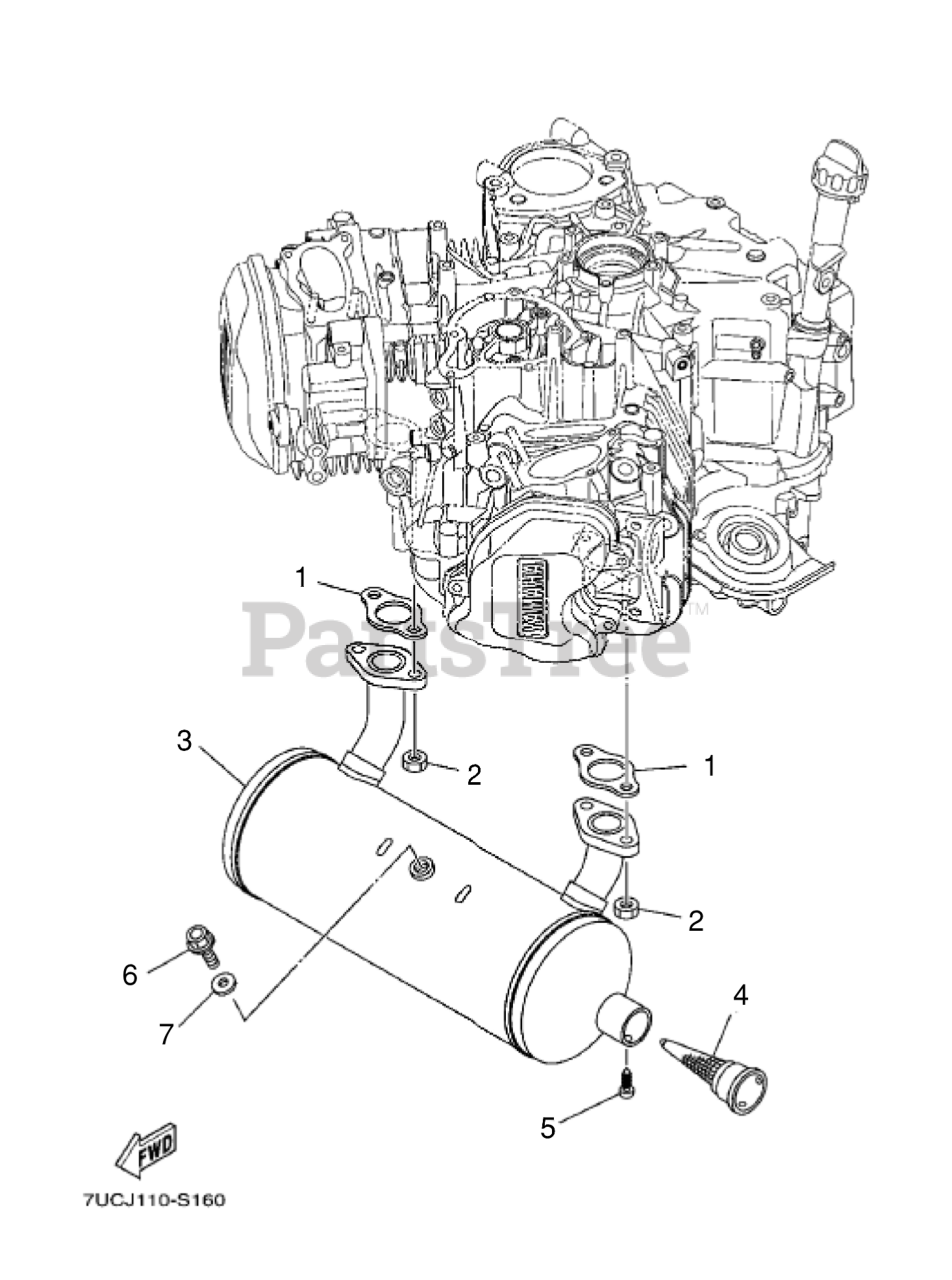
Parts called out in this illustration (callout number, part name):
1	GASKET EXHAUST PIPE YAMAHA PN:
2	NUT YAMAHA PN: 95302-08600
3	MUFFLER YAMAHA PN: 7UD-E4711-
4	ARRESTOR SPARK YAMAHA PN: 7UD-
6	BOLT YAMAHA PN: 90105-12809
7	WASHER YAMAHA PN: 90201-12172
